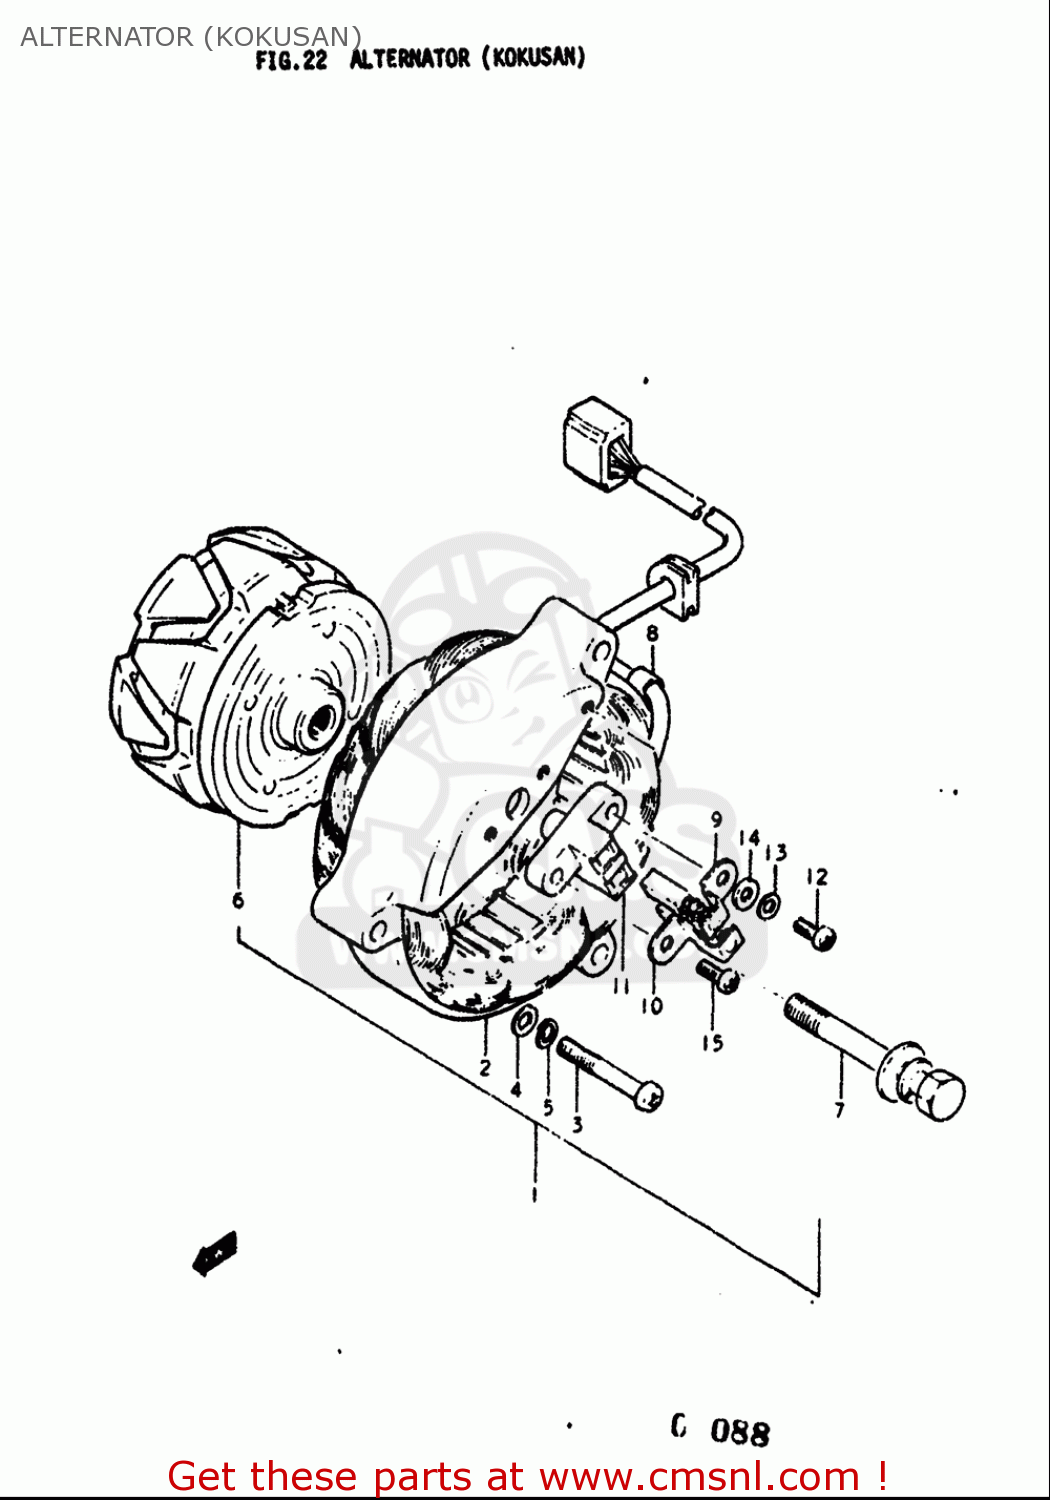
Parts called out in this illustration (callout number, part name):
4	WASHER
5	WASHER,LOCK
7	BOLT
9	BRUSH
10	BRUSH
12	SCREW 4X16
13	WASHER
15	SCREW
